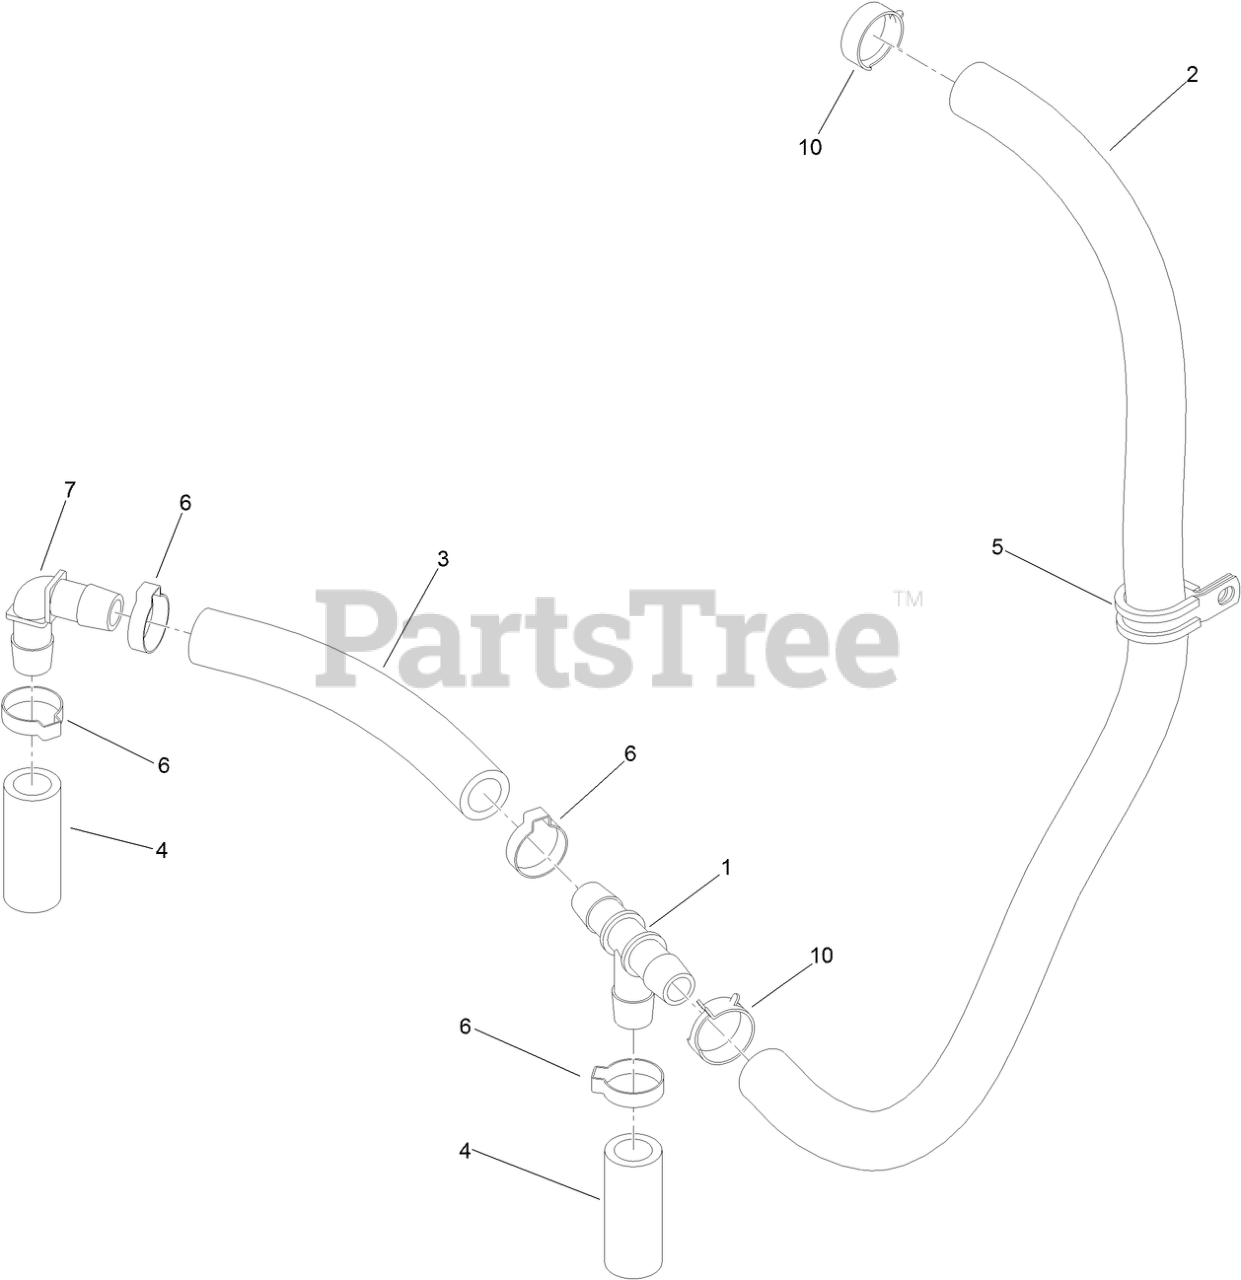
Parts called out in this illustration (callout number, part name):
1	FITTING TEE
2	HYDRAULIC HOSE
3	HYDRAULIC HOSE
4	HYDRAULIC HOSE
5	R-CLAMP
6	HOSE CLAMP, OETIKER
7	FITTING 90 DEG
10	CLAMP-SPRING
